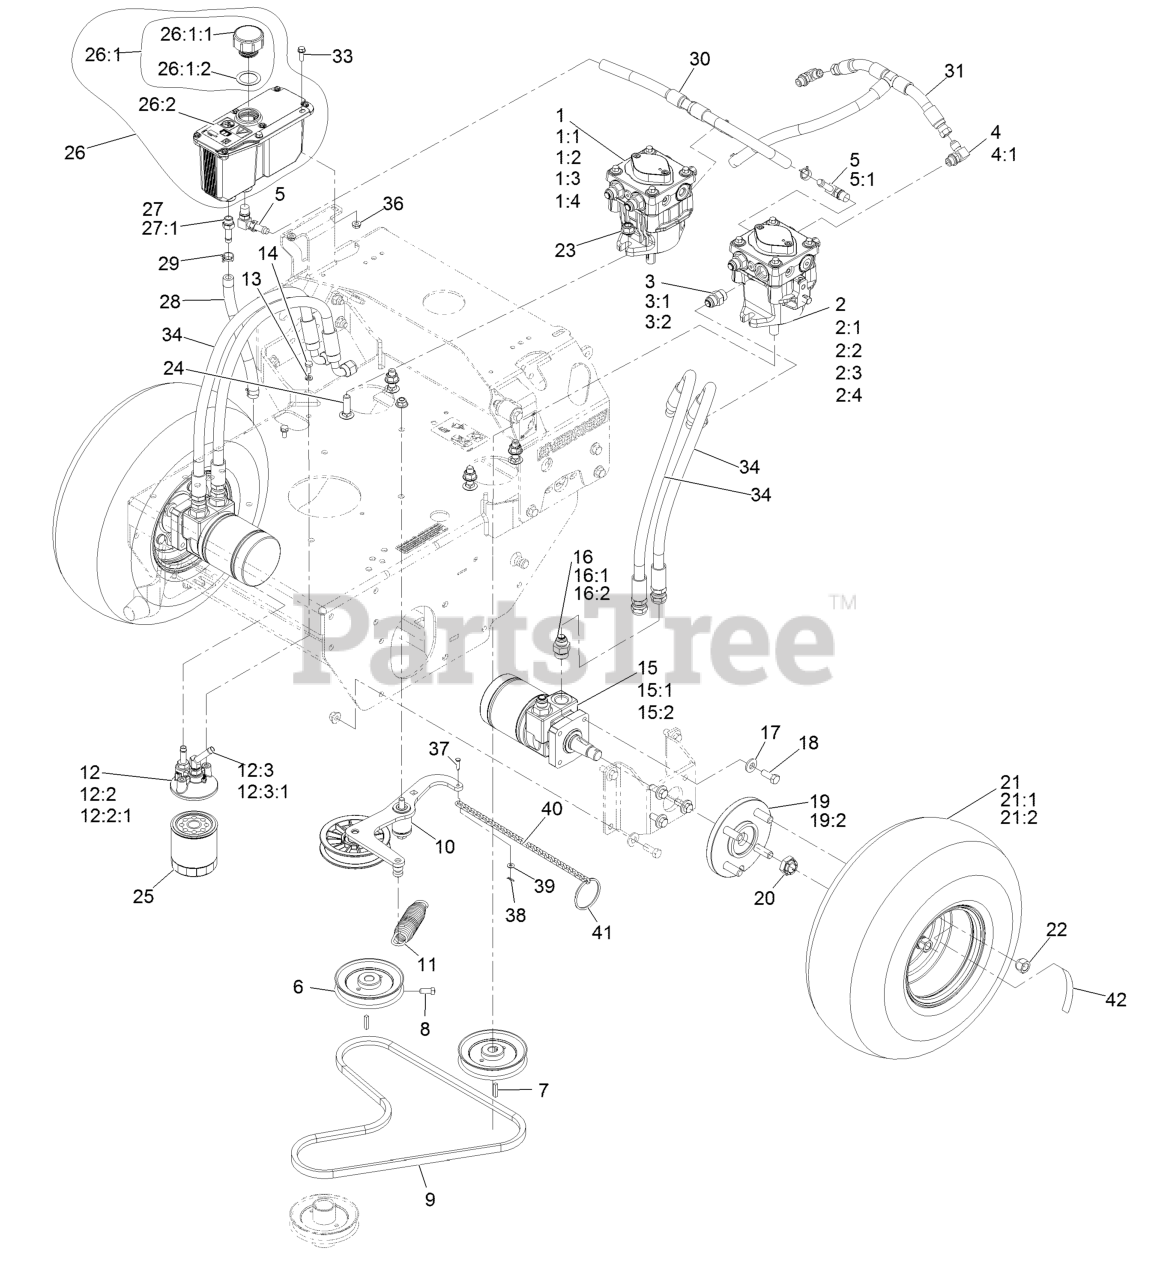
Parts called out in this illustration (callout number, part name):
1	RH HYD Pump ASM
1:1	Input Shaft Kit
1:2	Bearing-Thrust
1:3	Cylinder Block Kit
1:4	Seal Overhaul Kit
2	LH HYD Pump ASM
2:1	Input Shaft Kit
2:2	Bearing-Thrust
2:3	Cylinder Block Kit
2:4	Seal Overhaul Kit
3	Adapter-Straight
3:1	O-Ring-SAE #8
3:2	O-Ring-37 Flare #8
4	Fitting-Elbow, 90 DEG
4:1	O-Ring
5	Fitting-Elbow, 90
5:1	O-Ring
6	Sheave ASM
7	Key-5Mm X 5Mm X 25Mm
8	Screw-Set, SQH 5/16-18 X 3/4
9	Belt
10	ASM, Pump Idler
11	Spring-Extension
12	ASM, Filter Head
12:2	Adapter-Straight
12:2:1	O-Ring
12:3	Fitting-Barbed, 45 DEG
12:3:1	O-Ring
13	Washer-Lock 1/4 Heavy
14	Screw-HH 1/4-20 X 5/8
15	HYD Motor ASM
15:1	Seal Kit
15:2	Bearing And Seal Kit
16	Adapter-Straight
16:1	O-Ring
16:2	O-Ring-37 Flare #8
17	Washer-Spring Disc 3/8
18	Screw-HH 3/8-16 X 1
19	Wheel Hub ASM
19:2	Stud-Wheel
20	Nut-Lock
21	Wheel And Tire ASM
21:1	Tire-Turfmaster
21:2	Rim-Wheel
22	Nut-Lug 1/2-20
23	Nut-HF, NI
24	Bolt-Carriage 7/16-14 X 1 1/2
25	Element, Oil Filter
26	ASM, HYD Reservoir
26:1	Reservoir-HYD
26:1:1	Cap-Reservoir, HYD
26:1:2	Gasket-Cap
26:2	Decal-Warning
27	Adapter-Straight
27:1	O-Ring
28	Hose-Charge
29	Clamp-Hose 11/16
30	Hose-Case Drain
31	Hose-Charge
33	Screw-Machine 1/4-20 X 3/4
34	HYD Hose ASM
36	Nut-Whizlock 1/4-20
37	Pin-Clevis
38	Pin-Hair
39	Washer-Plain
40	Chain-Link, Twist
41	Ring-Split
42	Decal-Torque Wheel Lug-Hub
